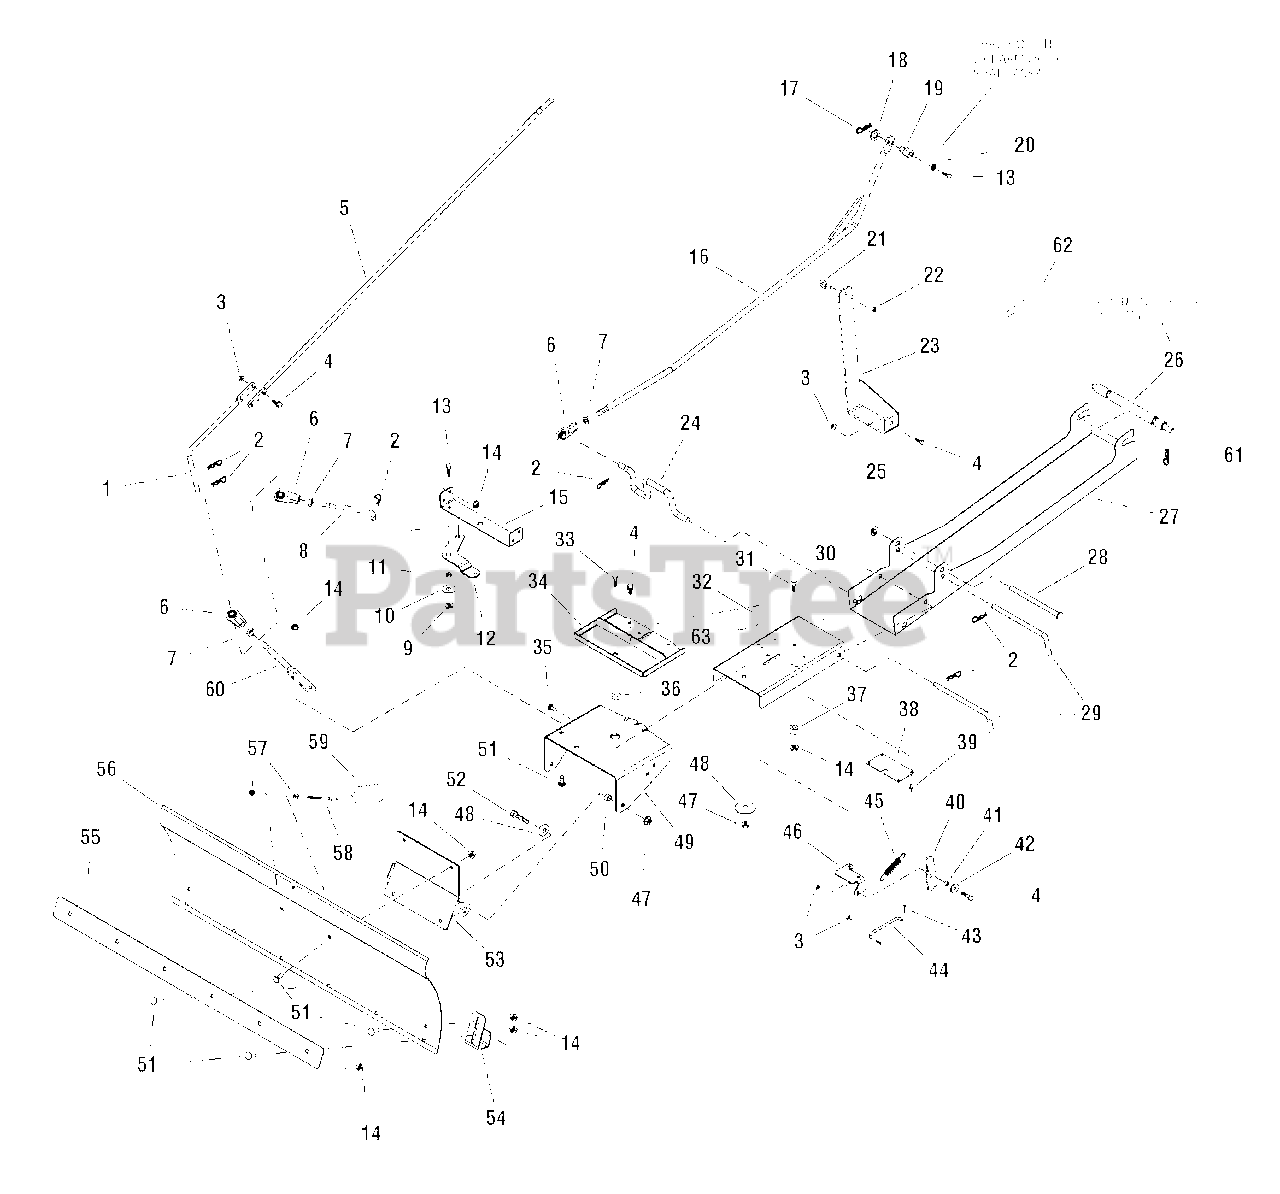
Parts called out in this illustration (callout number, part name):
1	ROD, 1/2 Diameter, 10.95 LG Angle w/Flat
2	PIN, Quick
3	NUT, Hex Flange, 5/16-18 ESNA
4	CAPSCREW, Hex Head, 5/16-18 x 1
5	ROD, 1/2 Diameter Angle w/Flat Top 49.2LG
6	JOINT, Ball
7	NUT, Hex Jam, 1/2-20
8	ROD, 1/2 Diameter 5.85 LG, Latch 1/2-20 x 1-1/2
9	NUT, Hex Lock ESNA Light 3/8-16NC3B
10	WASHER, 3/8
12	LEVER, Latch 7GA 42" Snow Blade
13	CAPSCREW, Hex Head, 3/8-16 x 7/8
14	NUT, Hex Flange 3/8-16 Whiz Lock Small
15	BRACKET, Cross, 42" Snow Blade, 10GA
16	ROD & BRACE ASSEMBLY, Lift, 42" Blade
17	CLIP, Hair Pin
18	WASHER, 5/8
19	PIVOT, Lift
20	LOCKWASHER, Spring
21	EYEBOLT, 1/4-20
22	NUT, Hex Lock ESNA Light 1/4-20
23	SUPPORT/BRACE ASSEMBLY, Rod 42"
24	ROD, 5/8 10.8 LG, Bellcrank
25	NUT, Push for 1/2 Diameter Stud Capped
26	ROD, 1"Diameter, 12.50 LG, Frame Latch
27	REACH, 42" Snow 12GA
28	ROD, 1/2" Diameter 7.62LG
30	HITCH, Lift 12GA
31	CAPSCREW, Hex Head 3/8-16 x 1-1/4 G5
33	CAPSCREW, Hex Head 1/2-13 x 1.35
34	BRACKET/BRACE ASSEMBLY, 42" Blade
35	CARRIAGE BOLT, 3/9-16 x 3/4
38	PLATE, Wear
39	RIVET, Pop
40	LATCH, Blade
42	WASHER, 3-5/16
43	COTTER PIN
45	SPRING, Extension
46	BRACKET, Latch
47	NUT, Hex Whiz Lock Flange, 1/2-13
48	WASHER, 1/2
49	HITCH, Pivot
51	CARRIAGE BOLT, 3/8-16 x 1
52	CAPSCREW, Hex Head, 1/2-13 x 1.35
53	PLATE, Backer
55	BAR, Scraper
56	BLADE, Snow
57	NUT, Hex 5/16-18
58	EYEBOLT, 5/16-18
60	ROD, 5/8" Diameter
61	PIN, Cotter, 1/8 x 1
62	SPRING. Extension, 5-3/32 Long
63	NUT, Push, Speed, 5/16 Dia.
